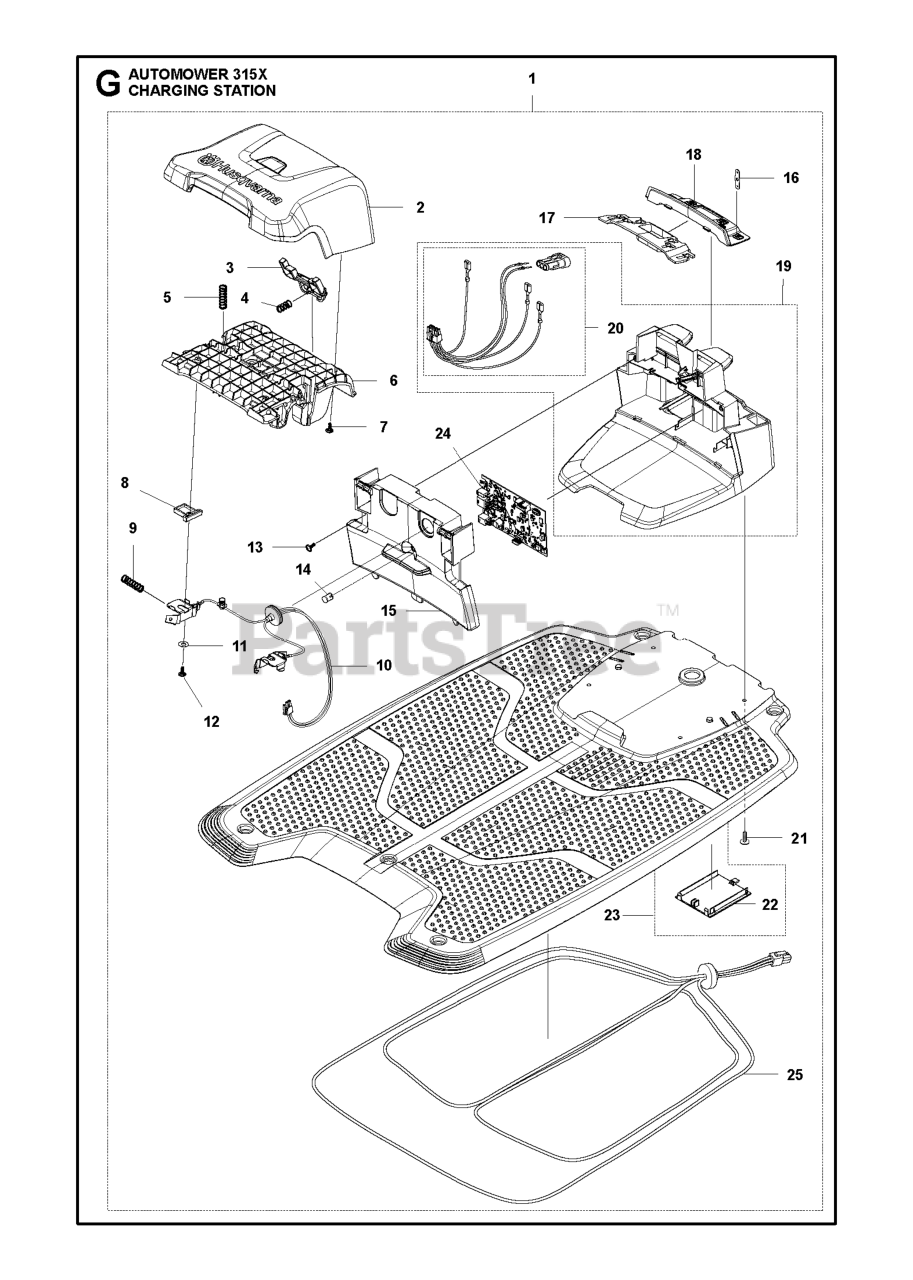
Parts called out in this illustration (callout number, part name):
1	CHARGING STATION ASSY HUSQVAR
2	CAP CHARGING STATION
3	BUTTON CHARGING STATION, RELEA
4	SPRING STOP BUTTON
5	SPRING SPRING CAP
6	FRAME CHARGING STATION
7	SCREW 14MM
8	DISTANCE CHARGING STATION
9	SPRING SPRING CAP
10	CABLE ASSY CHARGING CONTACTS
11	WASHER
12	SCREW 14MM
13	SCREW 14MM
14	LENS DIODE
15	LID CHARGING STATION
16	TERMINAL TERMINAL CHARGING STA
17	PAN CHARGING STATION 320, ONE
18	HOLDER CHARGING STATION
19	HOUSING ASSY CHARGING STATION
20	LOOM KIT GENERATOR BOARD
21	SCREW 14MM
22	COVER CHARGING PLATE
23	CHARGING PLATE KIT
24	Circuits
25	CABLE ASSY CHARGING PLATE SPAR
